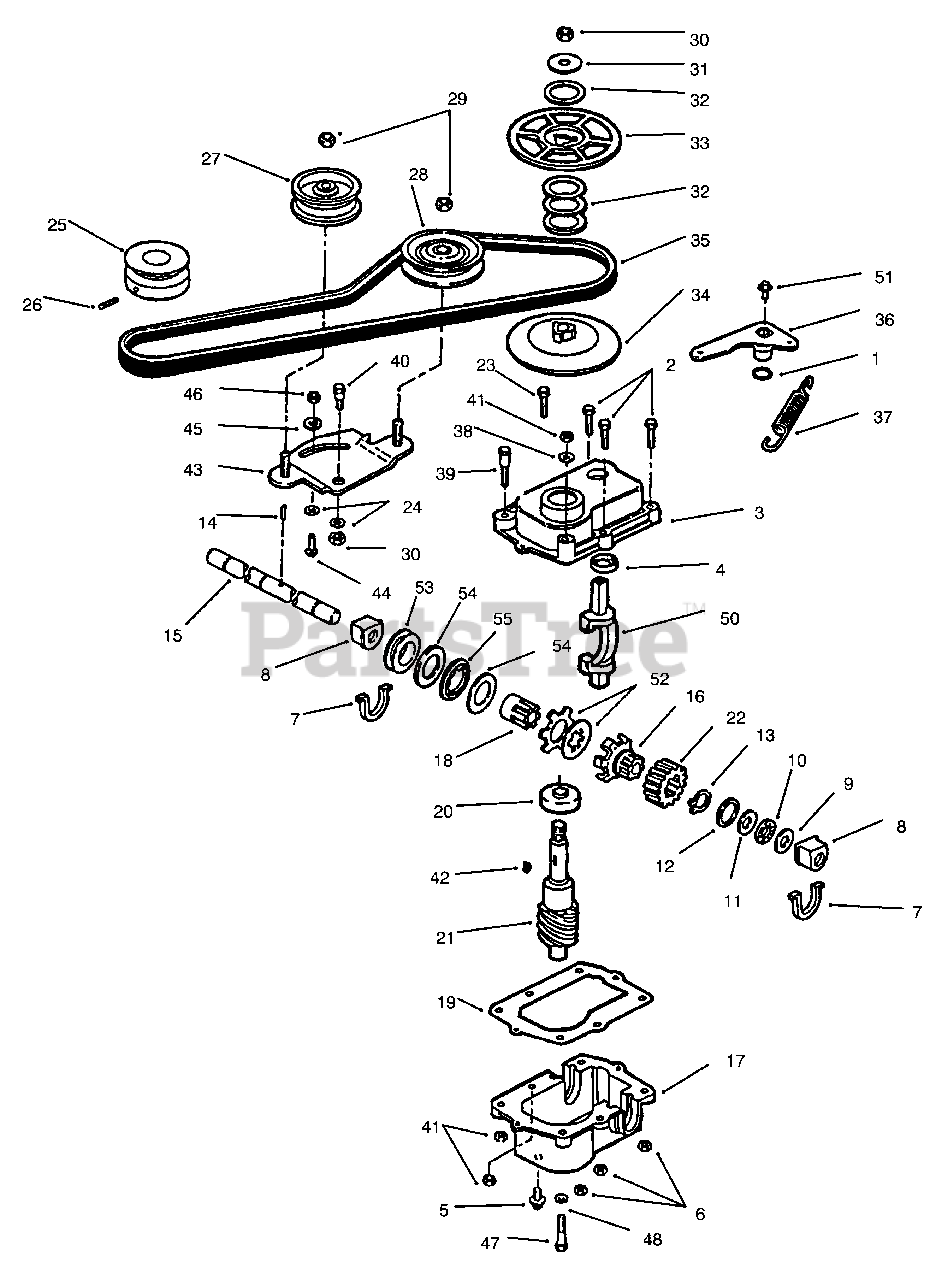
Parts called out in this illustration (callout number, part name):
2	Screw-Hex. Hd. Cap
3	Gearcase-Upper
4	Guide-Seal
6	Nut-Lock
7	Packing
8	Kit-Bearing & Seal
9	Washer-Thrust
10	Bearing-Thrust
11	Washer-Thrust
12	Washer-Thrust
13	Ring-Retaining
15	Shaft-Drive
16	Sleeve-Driven
17	Gearcase-Lower
18	Sleeve-Driver
20	Bearing
21	Kit-Worm Wheel & Shaft (Incl. Ref. #22)
22	Wheel-Worm
23	Screw-Hex. Hd. Cap
25	Pulley-Engine
26	Screw-Set
27	Pulley-Idler
28	Pulley-Idler, V-Belt
29	Nut-Pulley, Idler
31	Washer-Pulley, Drive
32	Washer-Pulley, Drive
33	Pulley Half-Upper
34	Pulley Half-Lower
36	Arm-Shift
37	Spring-Extension
39	Bolt-Shoulder
40	Bolt-Shoulder, Idler Plate
41	Nut-Lock
42	Key-Drive Pulley to Shaft
43	Plate-Idler
44	Bolt-Sq. Neck
48	Washer-Lock
50	Fork-Shift
51	Screw-SEMS
52	Kit-Disc Plate
53	Collar
54	Washer-Thrust
55	Bearing
